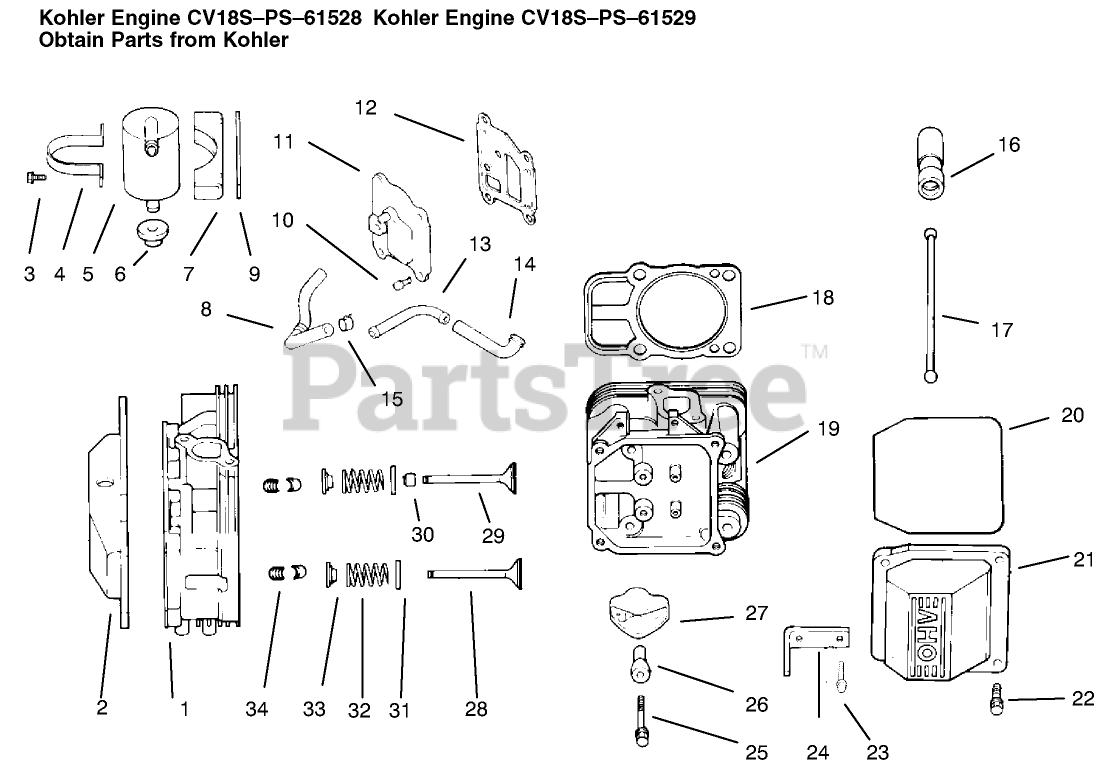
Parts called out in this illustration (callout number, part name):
1	Head ASM-#1 Cylinder (Only On: 72103, 72083)
2	Kit-Valve Incl 6 20-22
3	Screw M5x0.8x16 (Only On: 72042, 72063, 72062, 72043)
4	Strap-Lifting
5	Kit-Breather Incl 3-9
6	Grommet-Rubber (Only On: 72103)
7	Bracket
8	Hose-Breather
11	Cover-Breather (Only On: 72103)
12	Gasket-Breather
13	Fitting
14	Hose-Breather
15	Clamp
16	Lifter-Valve
17	Rod-Push
18	Gasket-Cylinder Head
19	Head ASM-#2 Cylinder (Only On: 72103, 72083)
21	Kit-Valve Cover (Incl. Ref. #2 3)
22	Screw-Shoulder
23	Screw
24	Strap-Lifting
26	Pivot-Arm, Rocker
27	Arm-Rocker
28	Valve-Exhaust
28	Valve-Exhaust (.25)
29	Valve-Intake
29	Valve-Intake (.25)
30	Seal-Valve Stem
31	Retainer-Spring
32	Spring-Valve
33	Cap-Valve Spring
34	Kit-Retainer
